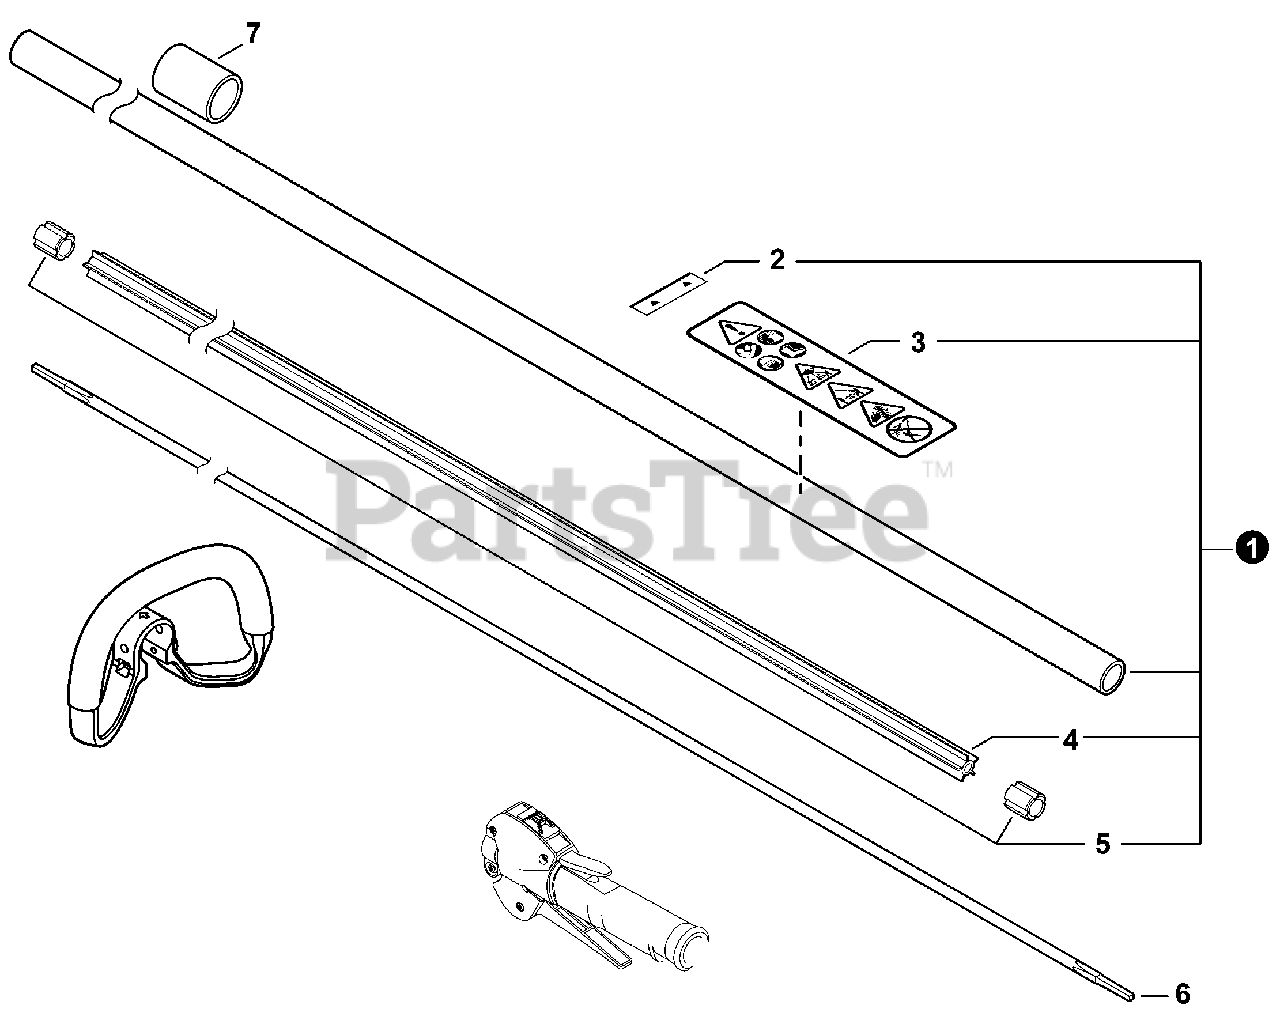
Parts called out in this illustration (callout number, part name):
1	MAIN PIPE ASSY
2	LABEL - ALIGNMENT
3	LABEL, CAUTION
4	LINER - FLEXIBLE
6	DRIVESHAFT - FLEXIBLE
7	COLLAR - 22
